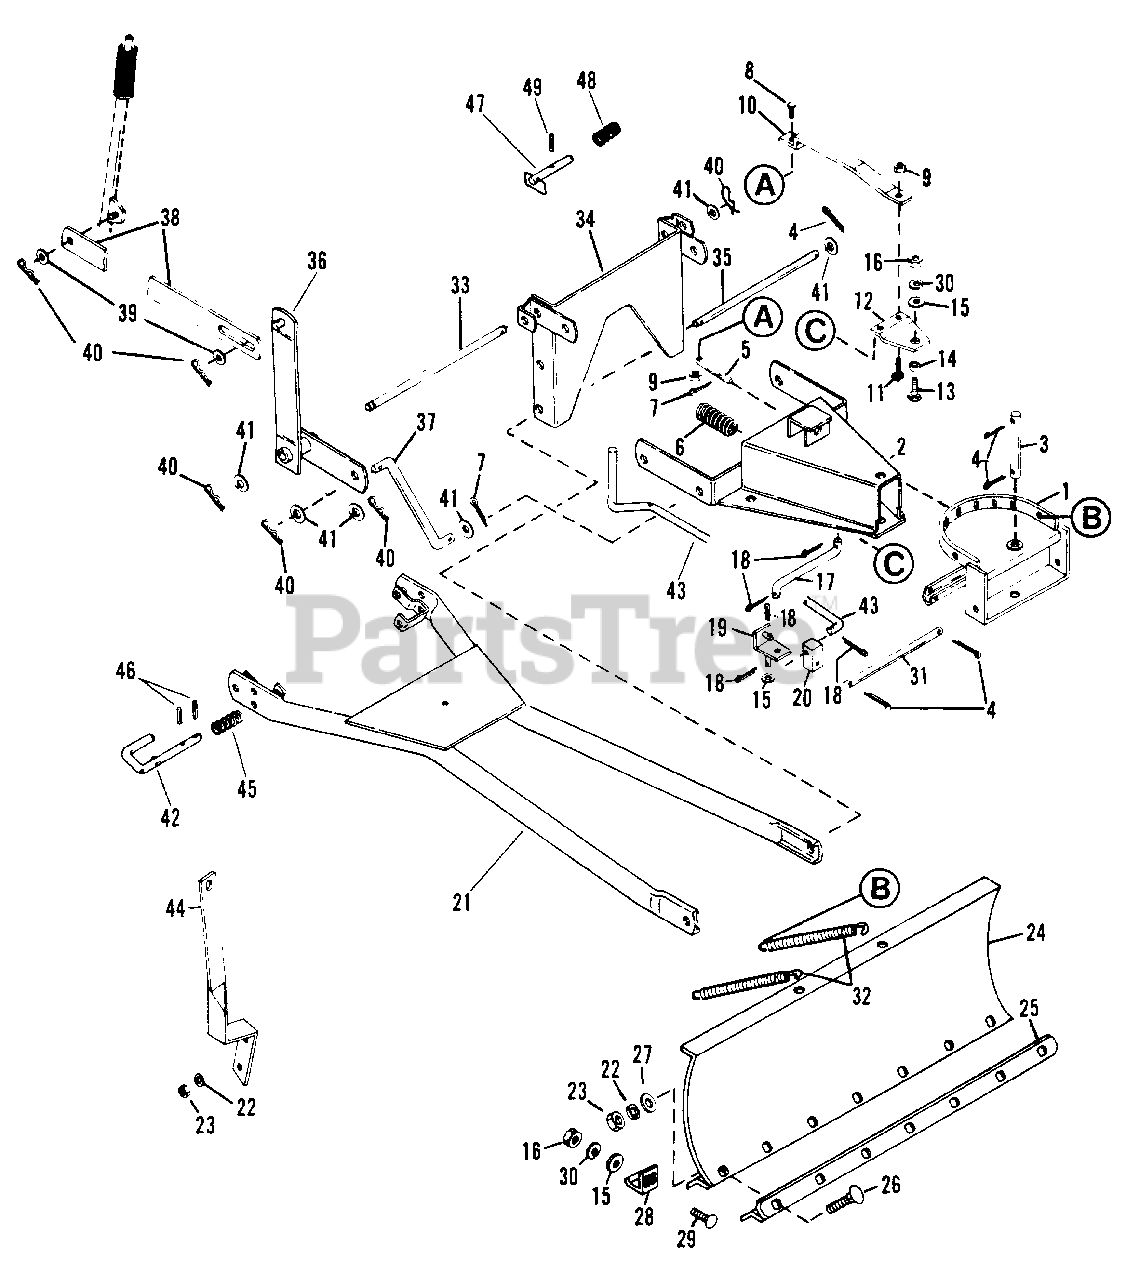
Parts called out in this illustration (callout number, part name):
1	Support
2	Push Frame
3	Rod
4	Cotter Pin 3/16x1.25
5	Latch Pin
6	Comp. Spring
7	Cotter Pin 1/8x1.00
8	Bolt, Hex 5/16-18x1.25
9	Nut, Lock 5/16-18
10	Strap
11	Bolt, 5/16-18x.625 Rd Hd Sq Nk
12	Pivot Plate
13	Bolt, Hex 3/8-16x1.00
15	Washer, Flat .438x1.000x.083
16	Nut, Hex 3/8-16
17	Rod
18	Cotter Pin 1/8x.75
20	Universal Block Joint
21	Carriage, Blade
22	Washer, Lock 5/16 SP
23	Nut, Hex 5/16-18
24	Blade
25	Wear Plate
26	Bolt, Carriage 5/16-18x1.00
27	Washer, Flat .406x.812x.065
28	Skid Shoe
29	Bolt, 3/8-16x1.00 Rd Hd Sq Nk
30	Washer, Lock 3/8 Reg.
31	Rod
32	Extension Spring
33	Mount Rod
34	Frame, Pivot
35	Pivot Rod
36	Lift Bellcrank
37	Lift Link
38	Lift Strap
39	Washer, Flat .500x1.250x.083
40	Hair Pin, Internal
41	Washer, Flat .656x1.312x.095
42	Pin, Latch
43	Control Rod
44	Control Support
45	Spring, Compression
46	Pin, Spring .125x.750
47	Pin, Lock
48	Spring
49	Pin, Spring .187x1.500
